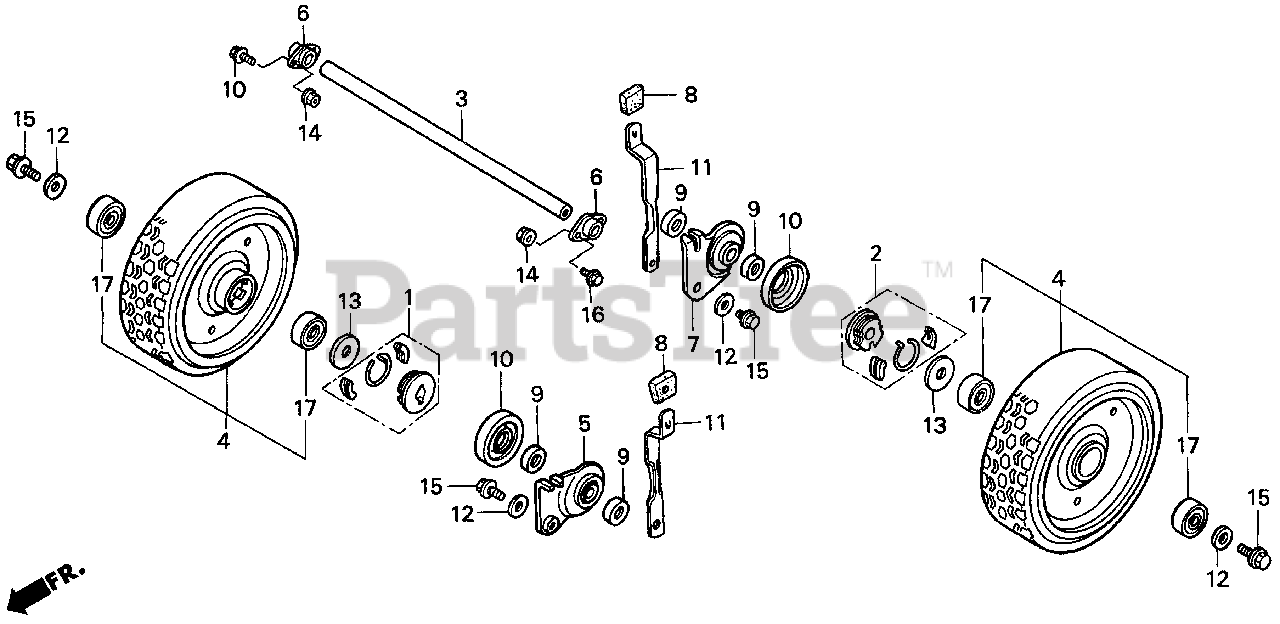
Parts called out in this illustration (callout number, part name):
1	HOLDER, R. RATCHET
2	HOLDER, L. RATCHET
3	SHAFT, RR. AXLE
4	WHEEL, PROPELLED
5	ARM, R. RR. ADJUSTER
5	ARM, R. RR. ADJUSTER (NOT AVAILABLE)
6	HOLDER, RR. AXLE
7	ARM, RR. ADJUSTER
7	ARM, RR. ADJUSTER (NOT AVAILABLE)
8	GRIP, ADJUSTER
9	COLLAR, DUST SEAL
10	CAP, DUST PROTECTOR
11	PLATE, RR. ADJUSTER
12	WASHER, RR. ENGINE MOUNTING
13	WASHER (16MM)
14	NUT, FLANGE (6MM)
15	BOLT, FLANGE (8X16)
16	BOLT, FLANGE (6X12)
17	BEARING, RADIAL BALL (6002UU)
NI	TIRE (9")
